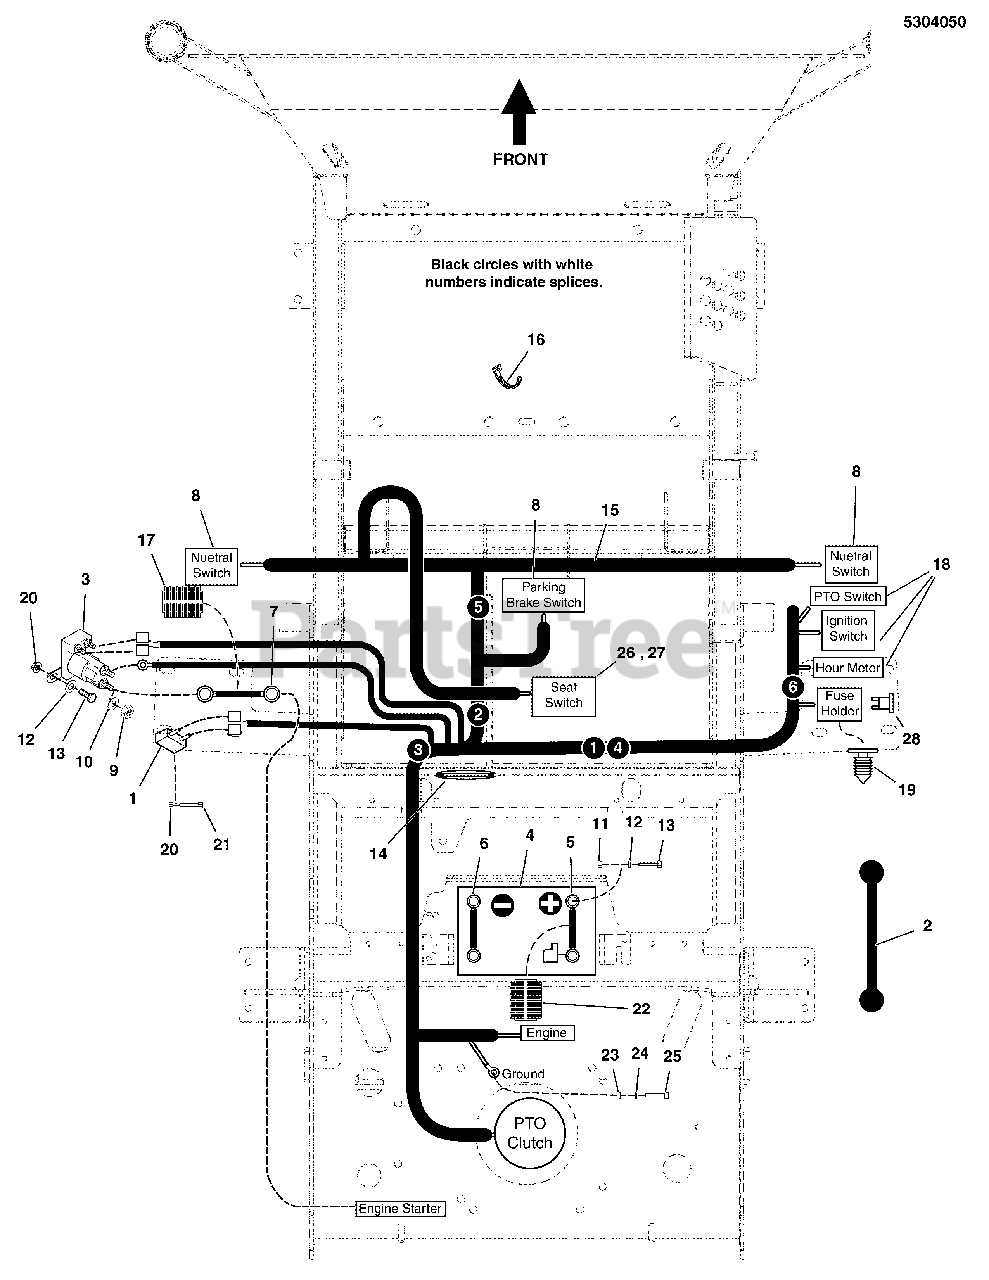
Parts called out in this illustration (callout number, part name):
1	BREAKER-CIRCUIT 12VOLT 20AMPS W/TAB
2	STRAP-BLACK RUBB
3	SOLENOID-4 POLE 12 VOLT DC (TROMBETTA)
4	BATTERY, WET ( BCIU1, 350 CCA)
5	BATTERY CABLE, POS, 15, 1/4-5/16
6	BATTERY CABLE, NEGATIVE, 10"
7	BATTERY CABLE, POS, 22, 1/4-5/16
8	SWITCH, PLUNGER, NO/NC SNAP-IN
9	NUT, 5/16-24 JAM
10	WASHER, 5/16 LIGHT LOCK
11	NUT, 1/4-20 HEX SERR. FLANGE
12	WASHER, 1/4 SAE
13	BOLT, 1/4-20 X 3/4 GD5 YZ
14	GROMMET, 1-1/2" ID FOR 1/4" METAL
15	WIRE HARNESS, C TURF, WARNER
16	TIE, SELF-LOCKING, 12"
17	WIRE LOOM, 3/8 ID X 18 IN
18	SEE INSTRUMENT CONTROL PANEL GROUP
19	FIR TREE MOUNT, PACKARD
20	NUT, 1/4-20 HEX NYLOCK FLANGE
21	SCREW,1/4-20X3/4, ZINC PHOS & OIL
22	WIRE LOOM, 3/8 ID X 12"
23	WASHER, 5/16 INT. TOOTH LOCK
24	WASHER, 5/16 SAE
25	BOLT, M8-1.25 X 20MM GD8.8
26	SEAT SWITCH, MILSCO, BOLT-IN (SV)
27	SEAT, SWITCH, MILSCO, TWIST-IN (SV)
28	FUSE, ATO 15 AMP (SV)
